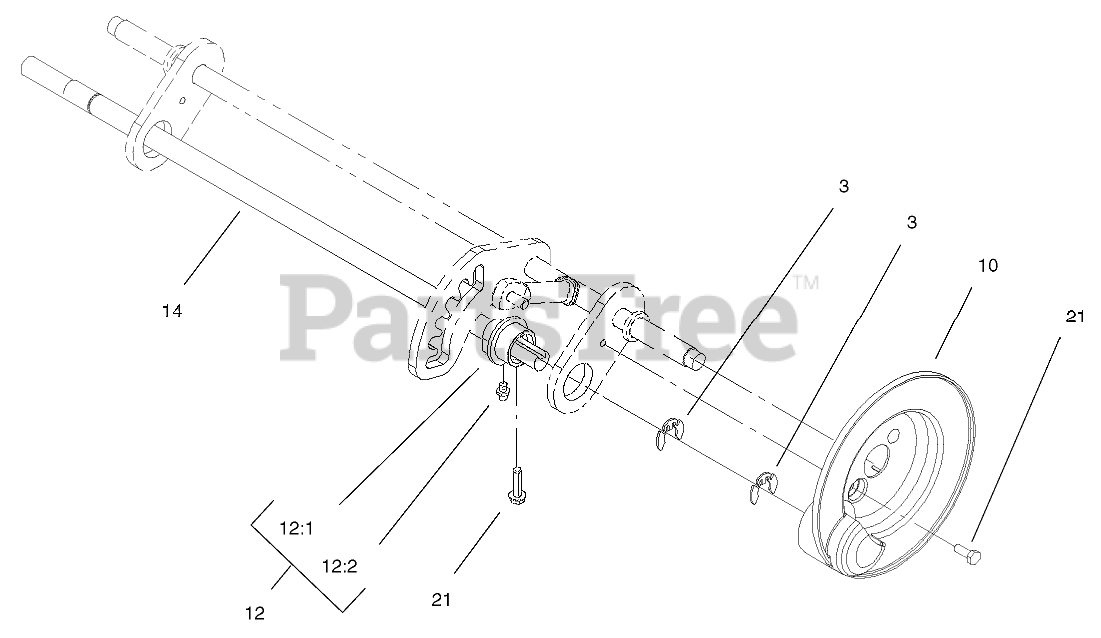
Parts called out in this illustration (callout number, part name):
3	RING-CLIP, LOCKING
10	COVER-GEAR
12	BUSHING ASM
12:1	BUSHING
12:2	FITTING-GREASE
14	SHAFT-PIVOT
21	SCREW-TAPTITE
